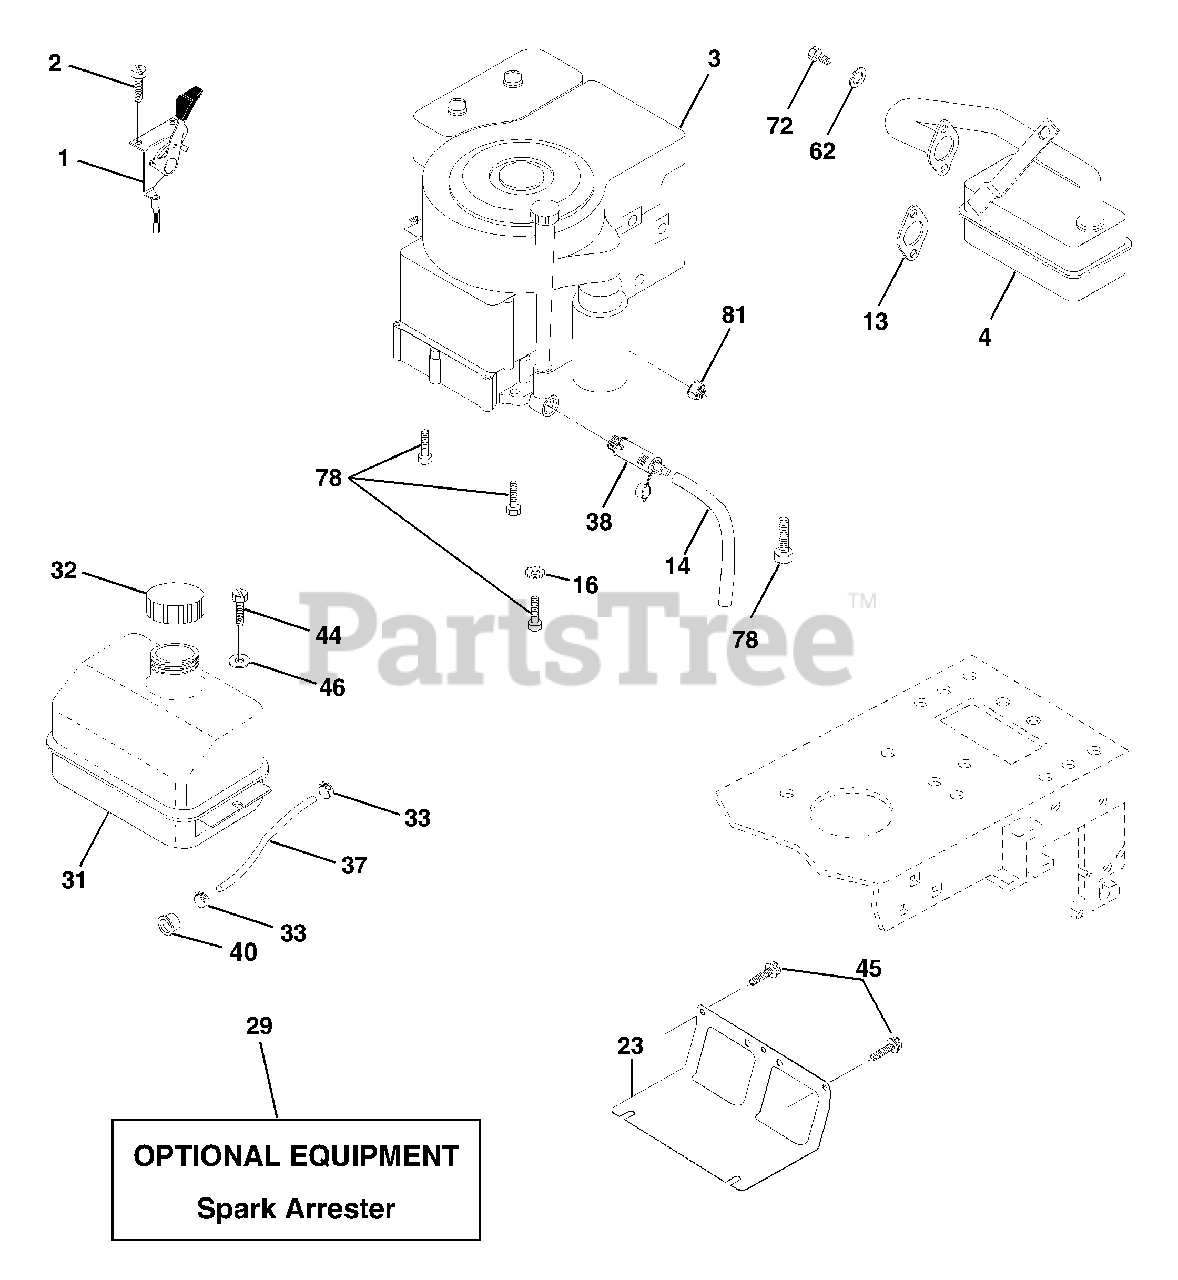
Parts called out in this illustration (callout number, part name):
1	Control Th/ch Flag
2	Screw Hex Thd Cut 1/4-20 x 1/2
13	Gasket Eng 1 313 Id Tin Plated
14	Tube Drain Oil Easy
16	Washer Lock Ext Tooth 3/8
23	Shield Brn/Dbr Guard
29	Kit Spark Arrestor (Flat Scrn)
31	Tank Fuel Front
32	Cap Asm Fuel W/sym Vented
33	Clamp Hose Black
37	Line Fuel 20"
38	Plug Drain Oil Easy
40	Bushing Snap Nyl Blk Fuel Line
44	Screw Hexwsh Thdrol 1/4-20 x 3/4
45	Screw Hexwsh Thdr 3/8-16 x 3/4
46	Washer 9/32 x 7/8 x 16 Ga
62	Washer Lock Hvy Hlcl Spr 5/16
72	Screw Hexhd Cap 5/16-18 x 3/4
78	Screw 3/8-16 x 1-1/4
81	Nut Keps Hex 1/4-20 Unc
